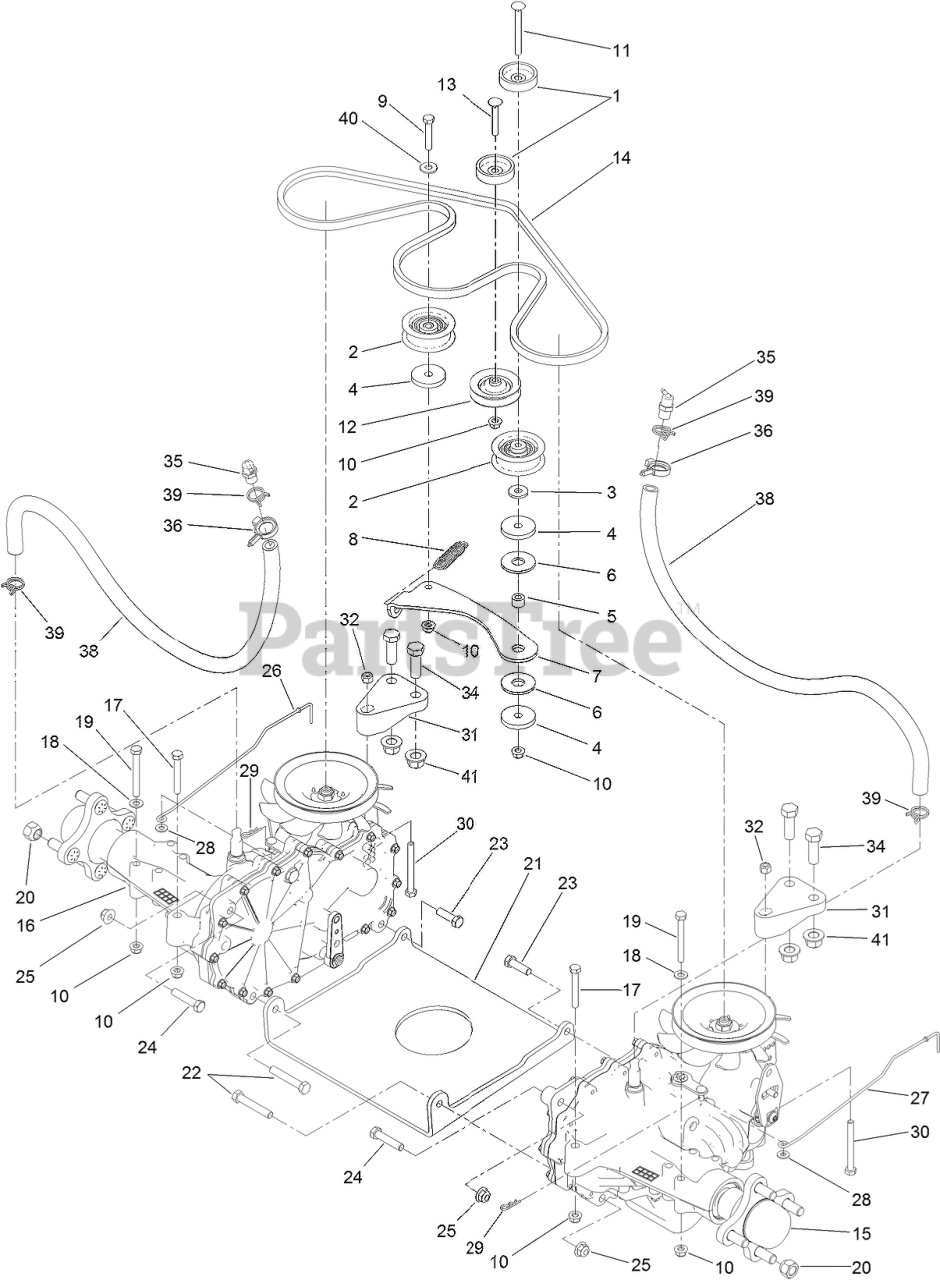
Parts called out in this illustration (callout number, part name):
1	SPACER
2	PULLEY-IDLER
3	WASHER
4	WASHER-PLAIN
5	BUSHING
6	WASHER-FRICTION, COMPOSITE
7	ARM-IDLER
8	SPRING-RETURN, PEDAL
9	SCREW-HH
10	NUT-HF, NI
11	SCREW-CARR
12	PULLEY-IDLER
13	BOLT-CARR
14	V-BELT
15	LH HYDRO TRANSMISSION ASM
16	RH HYDRO TRANSMISSION ASM
17	SCREW-HH
18	WASHER-PLAIN
19	SCREW-HH
20	NUT-LUG
21	PLATE-CROSS, HYDRO
22	SCREW-HH
23	SCREW-HH
24	SCREW-HH
25	NUT-HF, NI
26	ROD BYPASS, RH
27	ROD BYPASS, LH
28	WASHER-FLAT
30	SCREW-HH
31	SUPPORT-HYDRO, REAR
32	NUT-LOCK, NI
34	SCREW-HH
35	BREATHER KIT
36	CLAMP-HOSE
38	HOSE-HYDRO
39	CLAMP-HOSE
40	WASHER-FLAT
41	NUT-LOCK
